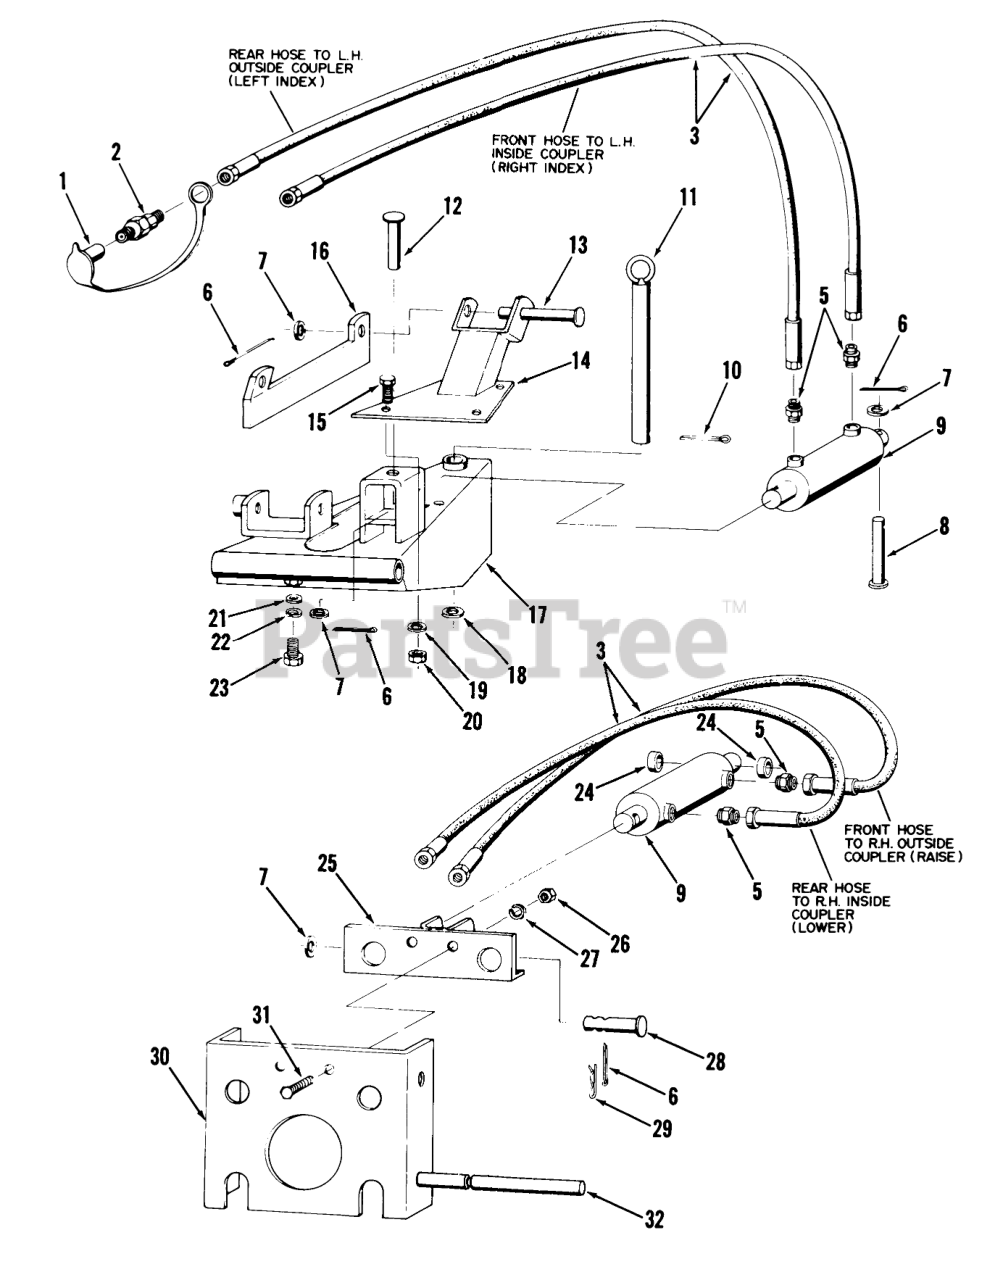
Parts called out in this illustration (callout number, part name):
1	DUST CAP
2	Coupling Plug
3	Hydraulic Hose
5	Straight Fitting (index Cylinder)
5	"L" Fitting
7	Washer
8	Clevis Pin
9	Hydraulic Cylinder
10	Cotter Pin
11	Pivot Pin
12	Clevis Pin
13	Clevis Pin
14	Lift Bracket
16	Transport Lock Bracket
17	A-Frame
18	Washer
19	Washer
21	Washer
22	Lockwasher
24	Spacer
25	Cylinder Support
27	Washer
28	Clevis Pin
29	Hairpin Cotter
30	Support Plate
32	Mounting Rod
